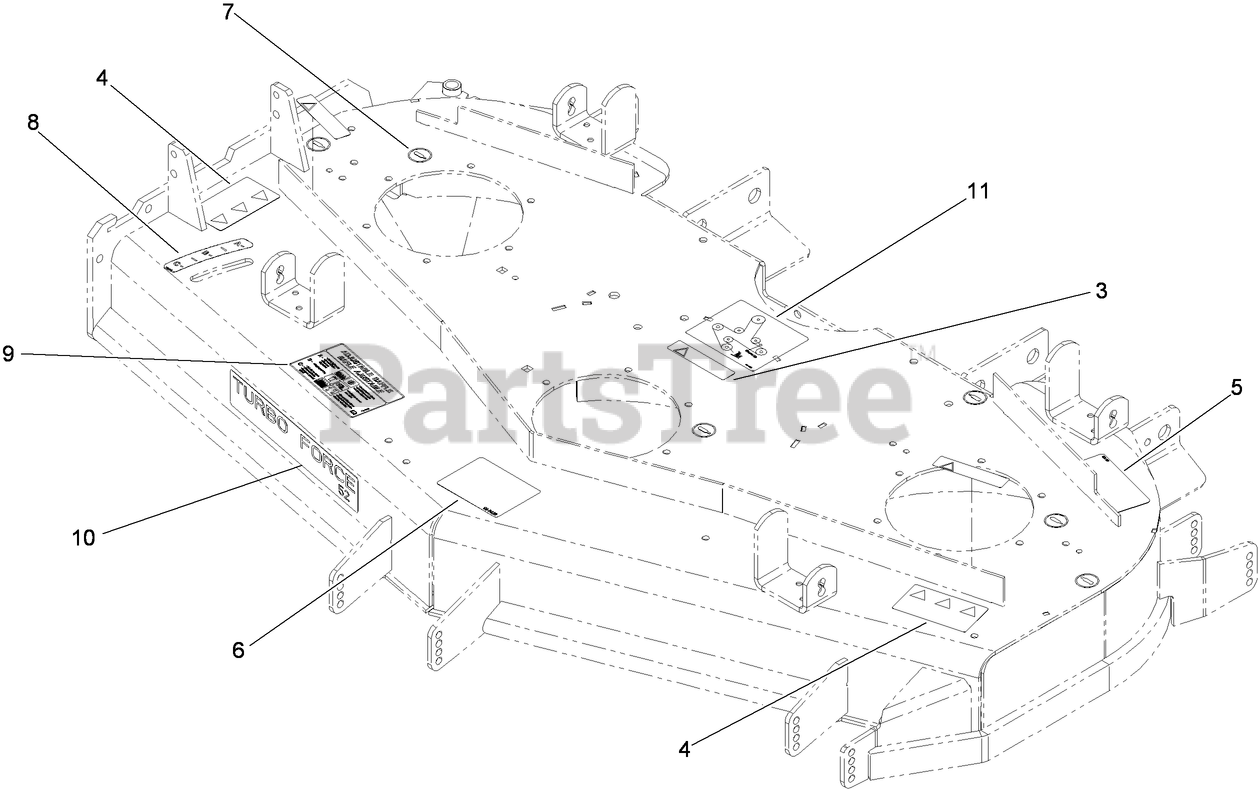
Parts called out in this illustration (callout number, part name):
3	DECAL-WARNING
4	DECAL-DANGER
5	DECAL-TORQUE, BLADE BOLT
6	DECAL-ANTI SCALP
7	DECAL-GREASE
8	DECAL-SETTING, BAFFLE
9	DECAL-ADJUSTMENT, BAFFLE
11	DECAL-ROUTING, BELT
